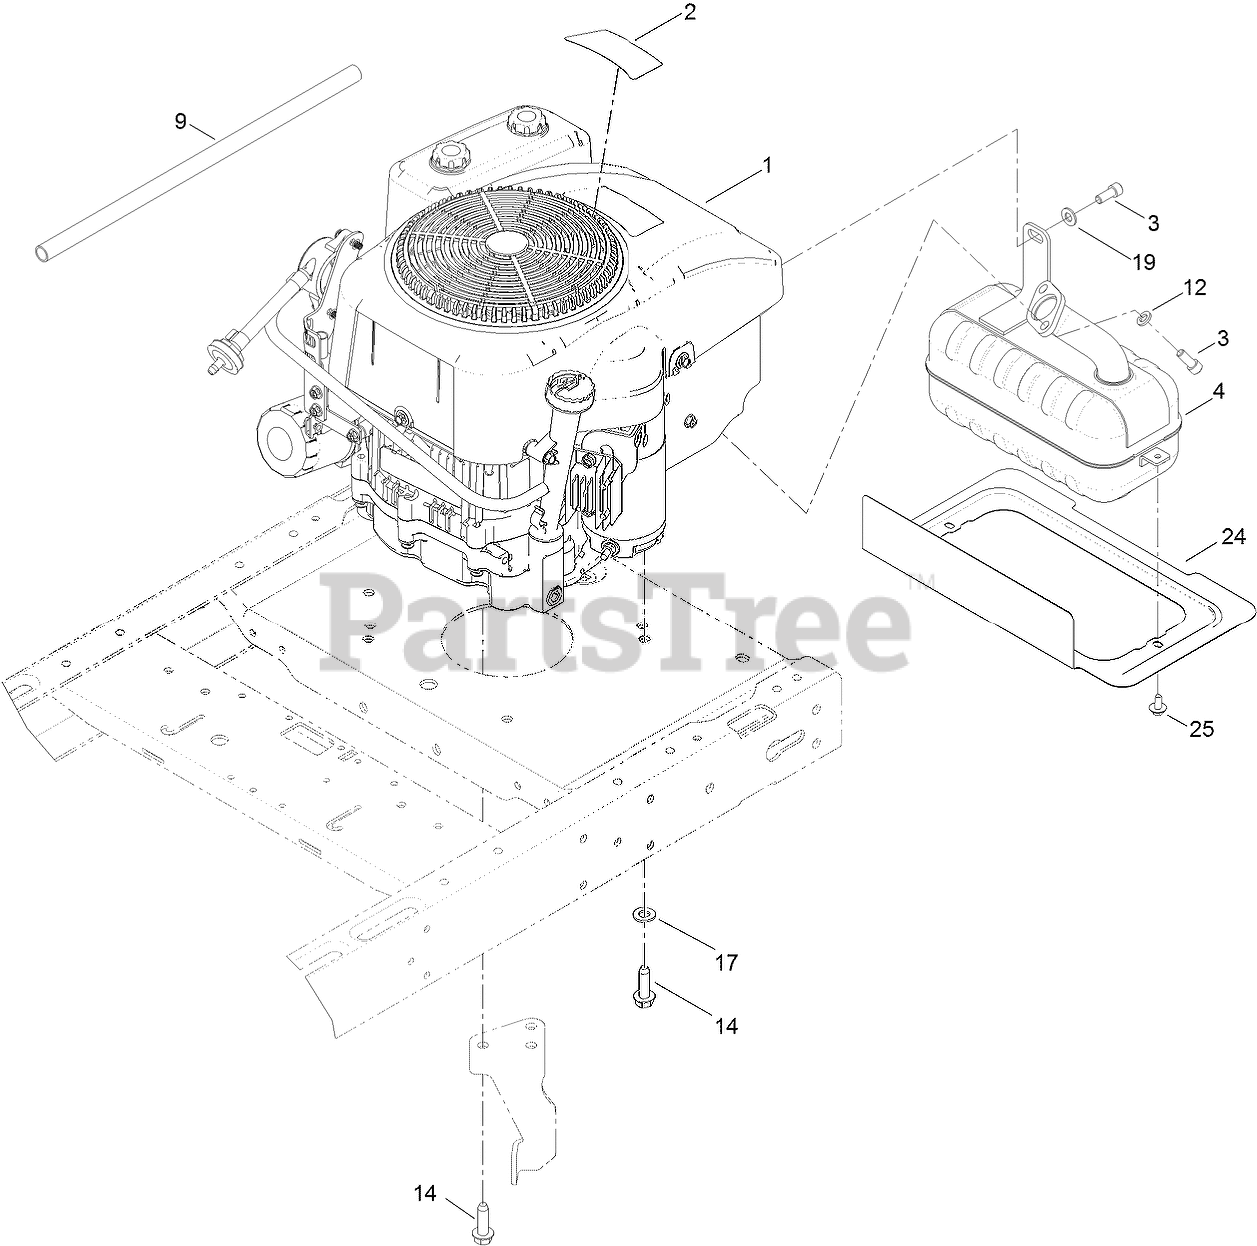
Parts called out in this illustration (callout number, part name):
1	ENGINE-LC1P92F-1
2	DECAL-ENGINE
3	SCREW-HSH
4	MUFFLER
9	TUBE-DRAIN, OIL
12	WASHER-LOCK
14	SCREW-TAPTITE
17	WASHER-FLAT
19	WASHER-PLAIN
24	SHIELD-HEAT
25	SCREW-HHFTF
